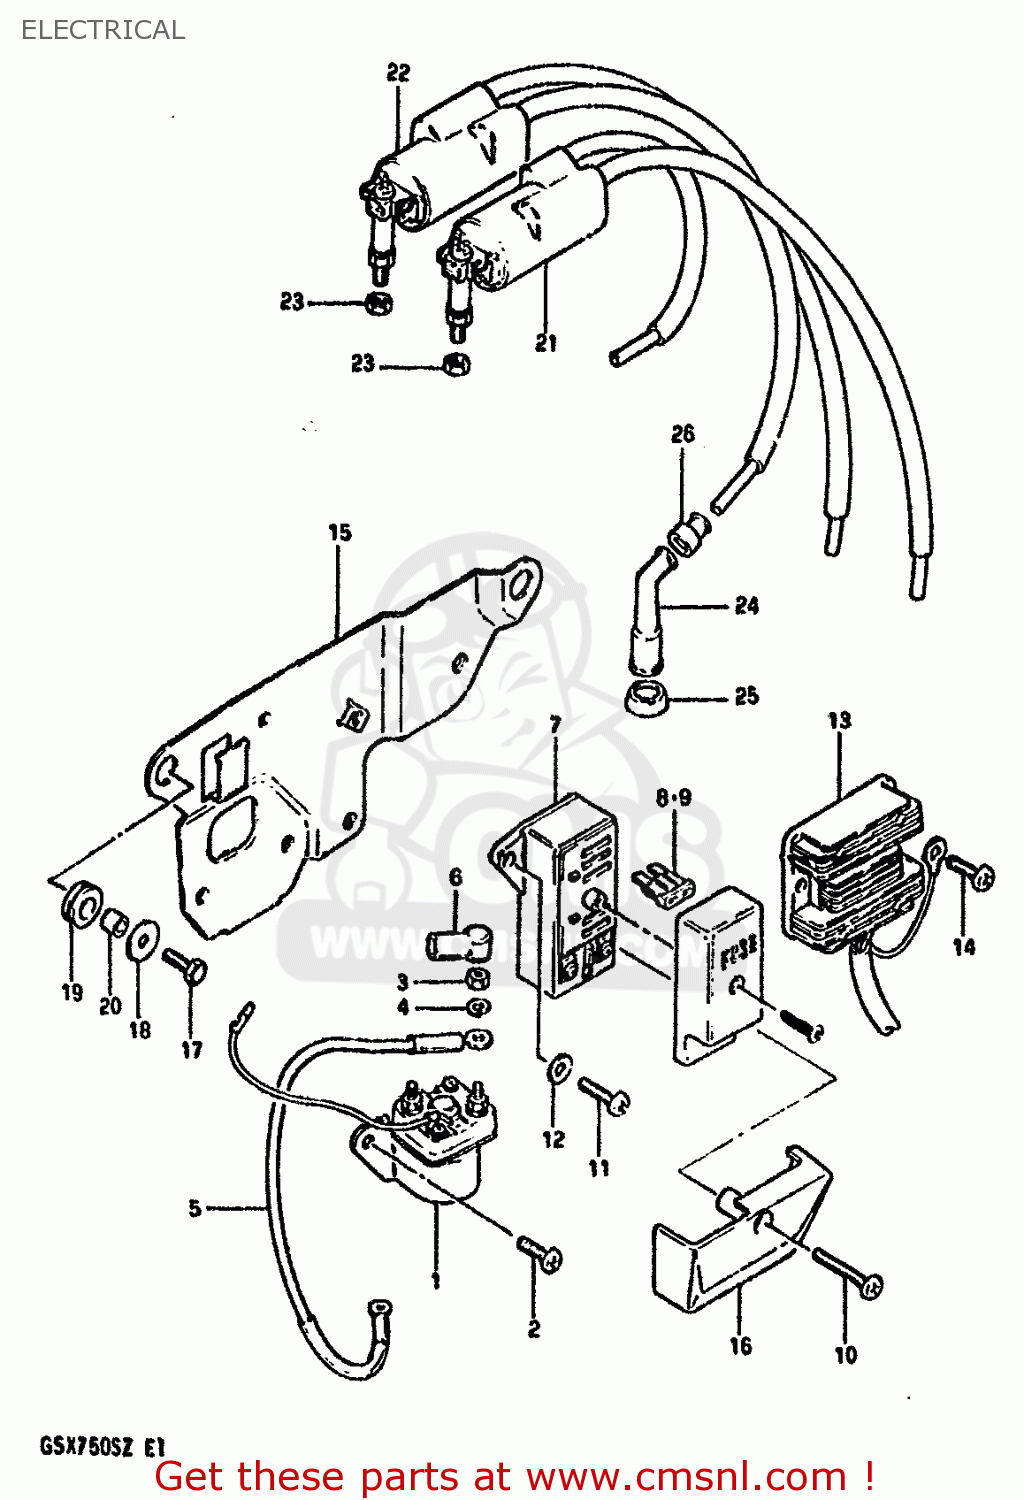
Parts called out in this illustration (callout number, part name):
1	RELAY, STARTING MOTOR
2	SCREW
3	NUT 6MM
4	LOCK WASHER
5	CORD,BATTERY MINUS
6	CAP,STARTER RELAY
7	BOX ASSEMBLY,FUSE
8	FUSE(10A)
9	FUSE(15A)
10	SCREW (6X35)
11	SCREW
12	WASHER
13	RECTIFIER, REGULATOR
14	SCREW 6X12
15	PLATE, PARTS HOLDER
16	COVER,ELECTRIC PARTS HOLDER
17	BOLT, UPPER
18	WASHER (6.5X22X1.6)
19	CUSHION
20	SPACER (7X9X7)
21	COIL ASSEMBLY,IGNITION
22	COIL ASSEMBLY,IGNITION
23	NUT
24	CAP ASSY,SPARK PLUG
25	SEAL,SPARK PLUG
26	SEAL,SPARK PLU
